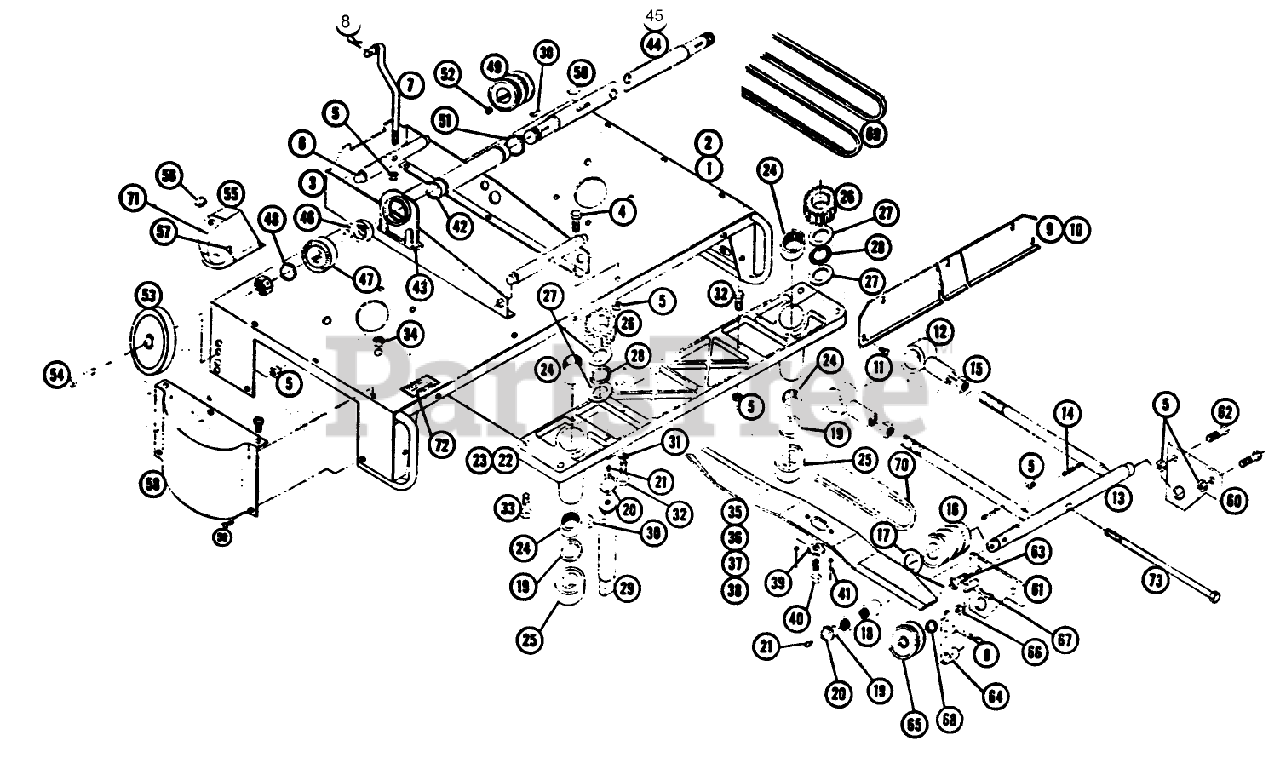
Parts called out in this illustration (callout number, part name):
4	Bolt 3/8-16 x 3/4
8	Hair Pin
14	ROLL PIN 1/8 X 1 1/2
15	Nut-5/8-18
17	WASHER
18	BEARING-NEEDLE
20	Snap Ring
27	WASHER-THRUST
30	Key #5 Woodruff
31	Lockwasher
33	Bolt 5/16-18 x 1
34	Nut-Nylok
37	SVC BULLT 99A
38	SVC BULLT 99A
40	Bolt 3/8-16 x 7/8
41	SPIROL ROLL PIN
43	BEARING SUPPORT
50	Key
54	Bolt-Shoulder
56	PLUG BUTTON
57	SCREW
60	Plate-Mtg. Bracket
62	Bolt 3/8-16 x 1
63	Bolt 3/8-16 x 1 RD.HD.
66	Nut, 1/2-20
67	Hair Pin Cotter
68	Lockwasher, 1/2 Ext.
69	V-BELTS - MATCHED PR
71	Decal
